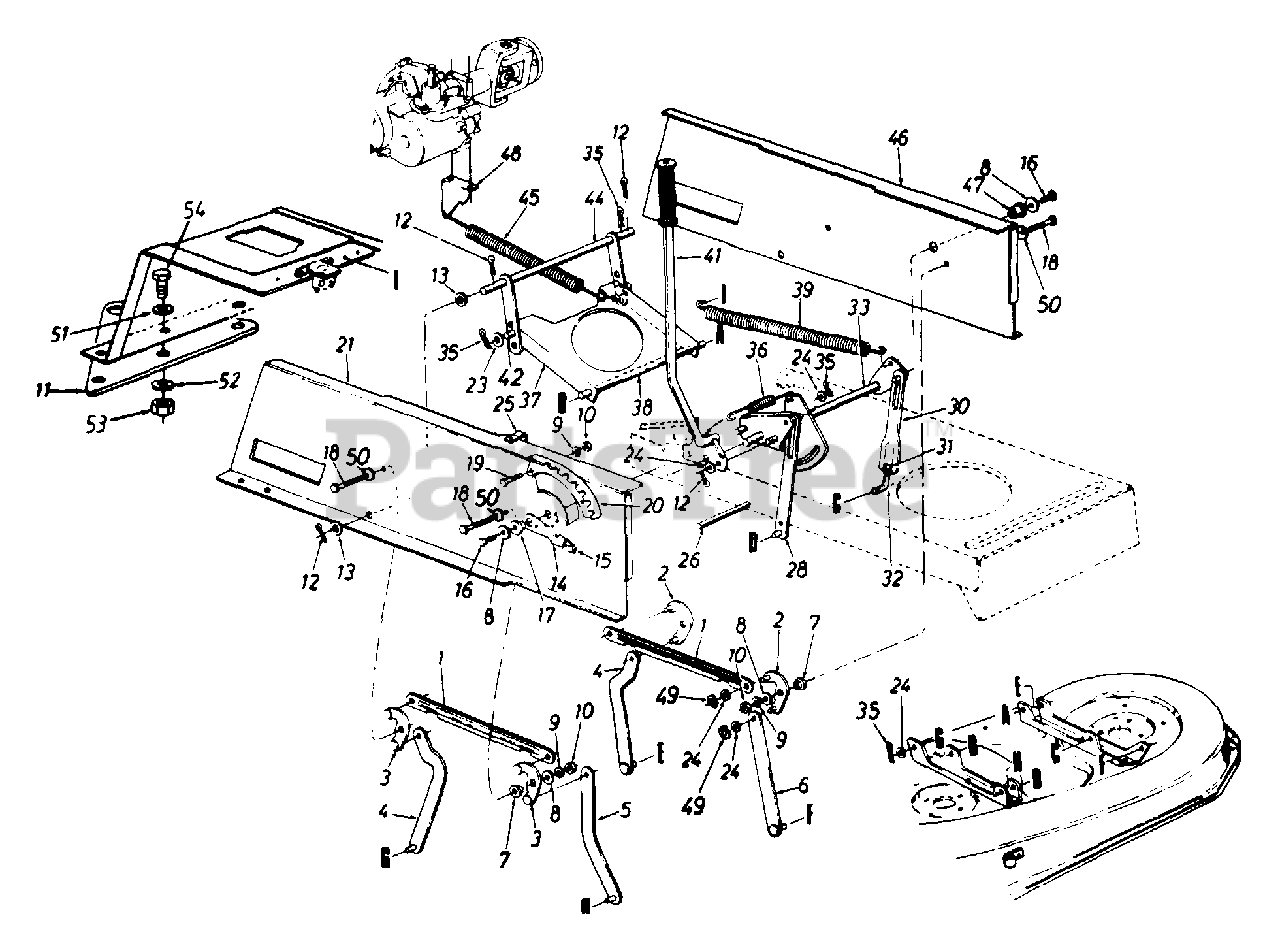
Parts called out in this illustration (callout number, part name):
3	Pivot Link Ass'y. - R.H.
7	Shld. Spacer .318" I.D.
8	Fl-Wash. .344" I.D. x .62" O.D.
9	L-Wash. 5/16" I.D.
10	Hex Nut 5/16-18 Thd.
11	Hitch Plate Extension
12	Cotter Pin 1/8" Dia.
13	Fl-Wash. .635" I.D. x 1.0" O.D.
14	Height Adj. Stop Lever Ass'y.
16	Hex Wash. TT-Tap Scr. 5/16-18 x .75" Lg.
17	Flange Brg. .63" I.D.
18	Hex Wash. Hd. Scr. 5/16-18 x .875" Lg.
19	Hex Bolt 5/16-18 x .75" Lg.
20	Index Brkt.
21	Upper Frame - R.H.
23	Fl-Wash. .385" I.D. x .87" O.D.
24	Fl-Wash. .531" I.D. x .93" O.D.
26	Running Board Rod
31	Hex Nut 1/2-20 Thd. (Gr. 5)
32	Lift Link Adjuster
36	Extension Spring
39	Extension Spring
41	Deck Lift Handle Ass'y.
42	Weld Pin
44	Stabilizer Shaft Ass'y.
45	Extension Spring 7.58" Lg.
46	Upper Frame - L.H.
47	Flange Brg. .632" I.D.
49	"E"-Ring
50	Bell-Wash. .325" I.D.
51	Bell-Wash. .46" I.D.
52	Fl-Wash. .469" I.D.
53	Hex Nut 7/16-14 Thd. (Gr. 5)
54	Hex Bolt 7/16-14 x 1" Lg.
